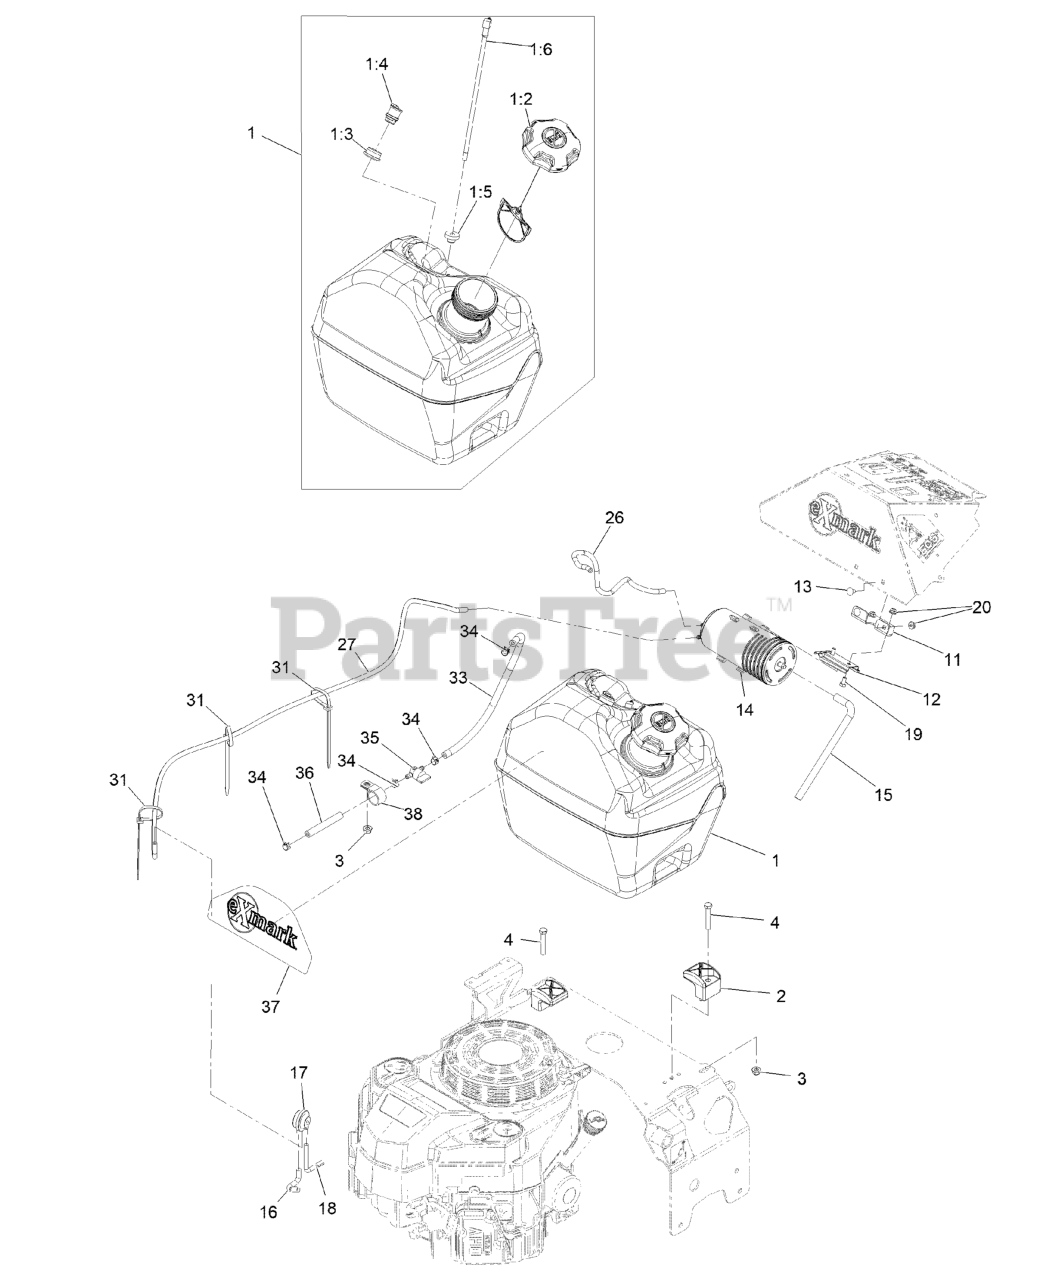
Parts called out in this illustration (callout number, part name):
1	Fuel Tank ASM, 5 Gal
1:2	CAP-FUEL, RATCHETING
1:3	GROMMET
1:4	VALVE-VENT, FUEL
1:5	BUSHING
1:6	FITTING, FUEL W/LINE AND SCREEN
3	NUT-HF, NI
4	SCREW-HH
11	BRACKET-CANISTER, CARBON
12	BRACKET-CANISTER, CARBON
13	SCREW-CARR
14	CANISTER-CARBON, 800CC
15	HOSE-VENT, CANISTER
16	HOSE-VENT, FORMED
17	VALVE-CONTROL, VACUUM
18	HOSE-VENT, FORMED
19	SCREW-HH
26	HOSE-EMISSIONS
27	HOSE-VENT, FORMED
31	TIE-CABLE
33	HOSE-FUEL
34	CLAMP-HOSE
35	VALVE-FUEL
36	HOSE-FUEL
37	Artwork-Exmark Logo Fuel Tank
38	CLIP-LOOM
